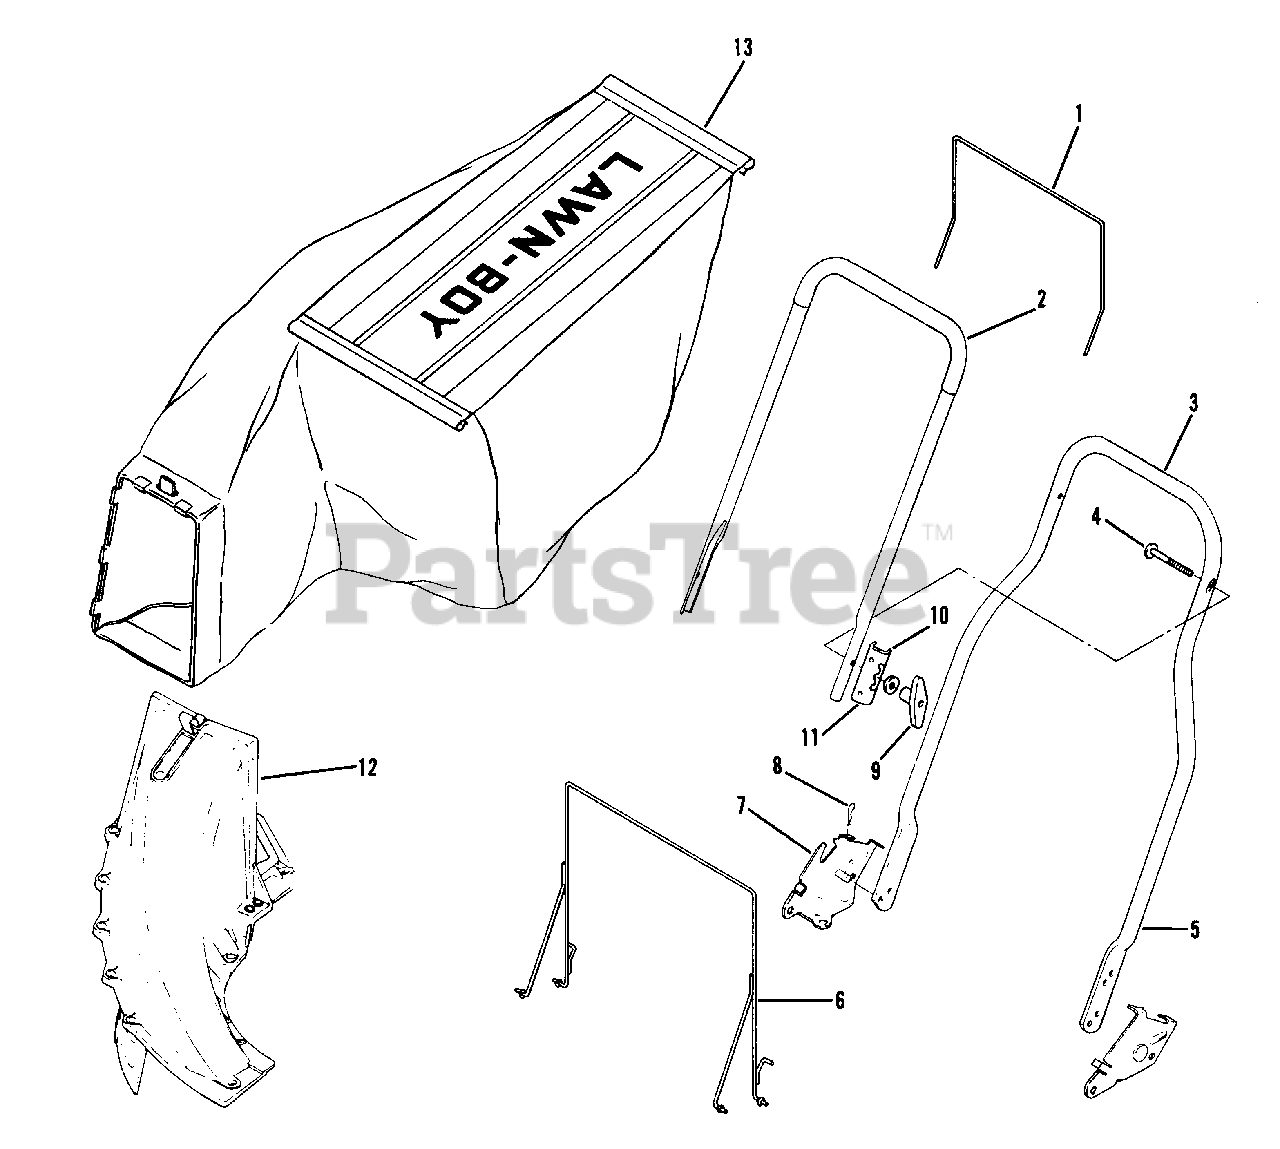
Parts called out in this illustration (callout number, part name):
1	Hanger Rear
2	Top Handle & Grip Assembly
3	Handle Section-Bottom
4	Screw
5	Handle Bracket-L.H.
6	Hanger Assembly-Front
7	Handle Bracket-R.H.
8	Lock Pin
10	Washer-Curved
11	Bracket-Rear Hanger
12	Chute Assembly
13	Bag & Deflector Assembly
